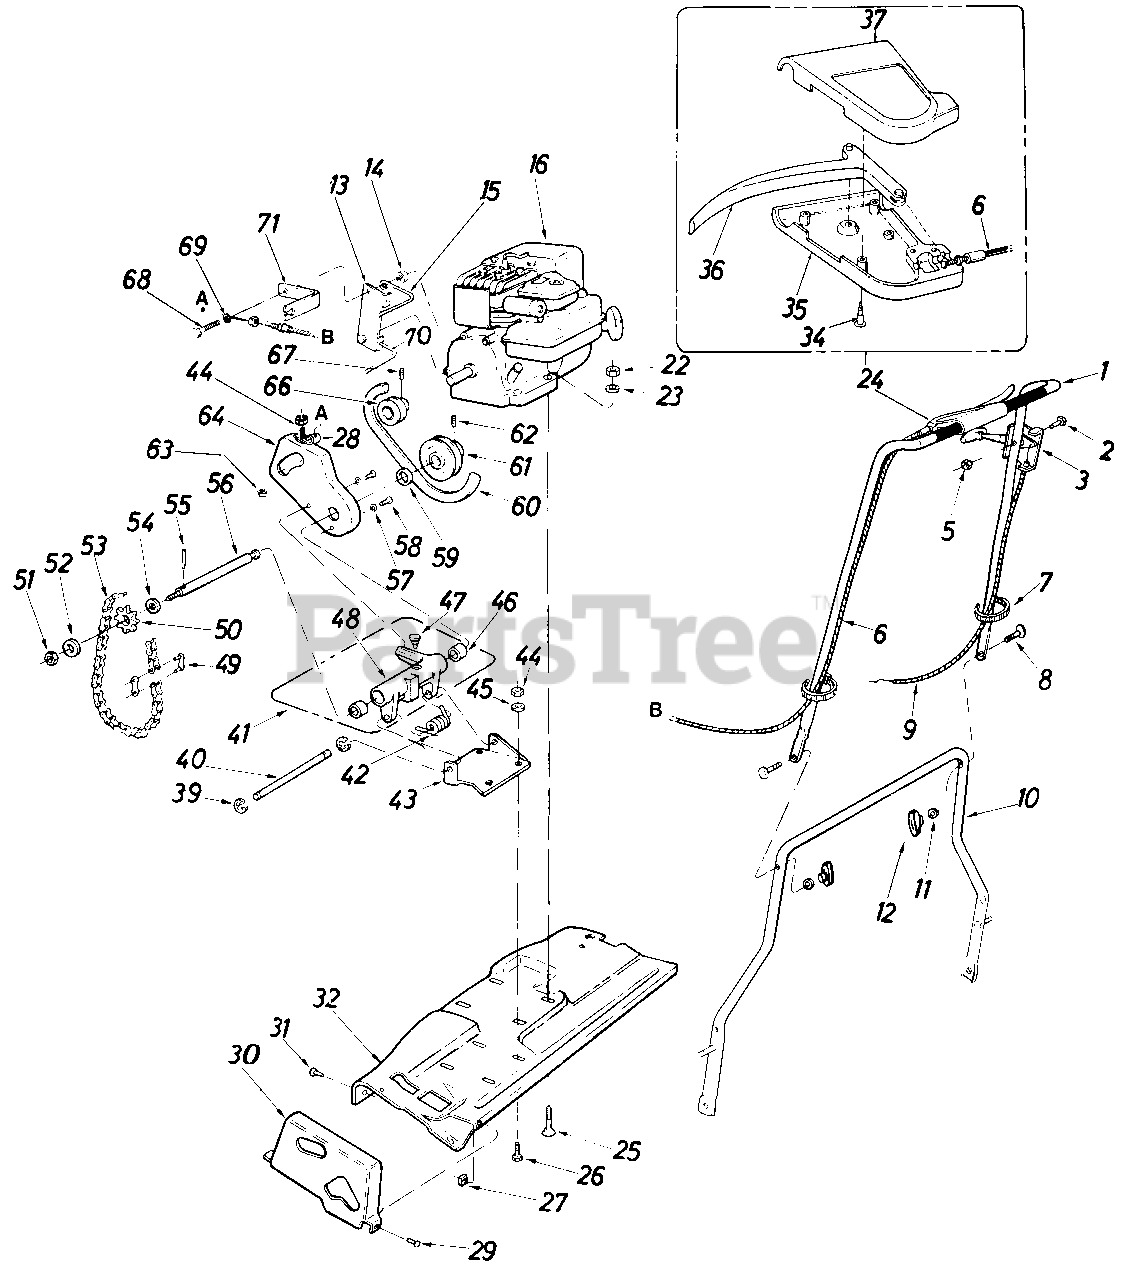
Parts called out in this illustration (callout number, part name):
1	Upper Handle Ass'y.
2	Rd. Hd. Scr. 1/4-20 x 1.88" Lg.
3	Throttle Control Ass'y.
5	Capped Wash . Z-Nut
6	Clutch Control Cable
7	Cable Tie
8	Special Scr. 5/16-18 x 1.75" Lg.
9	Throttle Cable
10	Lower Handle Ass'y.
11	L-Wash. 5/16
12	Handle Knob
13	Belt Keeper Brk't.
14	Spacer
15	Belt Keeper Upper
22	Hex Nut 5/6-18 Thd.
23	L-Wash . 5/16
24	Clutch Control Ass'y.
25	Carriage Bolt 5/16-18 x 1.375" Lg.
26	Scr. 1/4-20 x .625" Lg.
27	Hex L-Nut 10-32 Thd.
28	Clevis Lanyard Fitting
29	Ph. Hd. Scr. 10-32 x .375" Lg.*
30	Chain Guard
31	Hex Sems Scr. 5/16-24 x .50 Lg.
32	18" Deck
34	Slotted Oval Self-Tap Scr. #10 x .87" Lg.
35	Rear Control Cover
36	Lever Ciutch Control
37	Front Cover Control
39	Retaining Ring
41	Jack Shaft Hsg. and Brg. Ass'y.
42	Spring
43	Bracket
44	Hex Nut 1/4-20 Thd.
45	1/4 Split L-Wash.
46	Bearing
47	Oiler
48	Jack Shaft Hsg.
49	Connector Link
50	Sprocket
51	Hex Jam Nut 5/16-24
52	Washer
53	Chain
54	Wash. 5/8 x 15/16
56	Jack Shaft
57	Washer
58	Ph. Hd. Scr. 10-32 x .50" Lg.
59	Wash. 5/8 x 15/16
60	"V" Belt
61	Pulley Ass'y.
62	Roll Pin
63	Hex Nut 1/4-20 Thd.
64	Belt Guard Ass'y.
66	Pulley
67	Set Scr. 5/16-24 x 7132" Lg.*
68	Ph. Hd. Scr. 1/4-20 x 1.75" Lg.
69	L-Wash. 1/4" Scr.
70	Belt Keeper Lower
71	Clutch Cable Bracket
